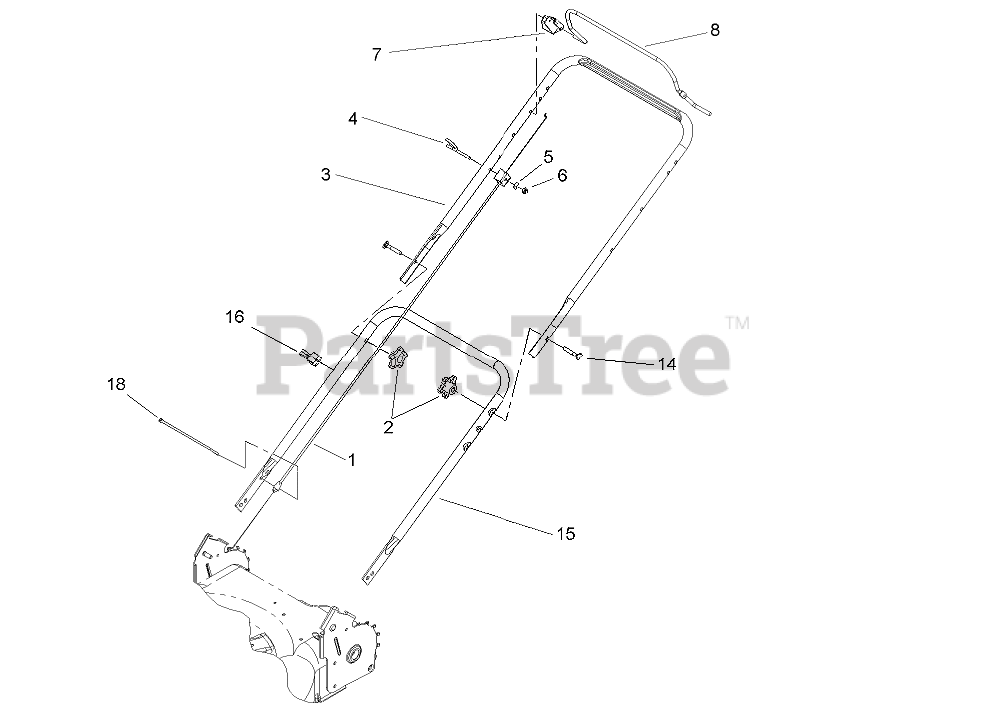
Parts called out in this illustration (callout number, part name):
1	Cable-Brake
2	KNOB-HANDLE
3	Handle-Upper
4	GUIDE-ROPE
5	WASHER-FLAT
6	NUT-LOCK, NI
7	STOP-PIVOT
8	Bail-Brake
14	SCREW-HANDLE
15	HANDLE-LOWER
16	Guide-Cable
18	TIE-CABLE
